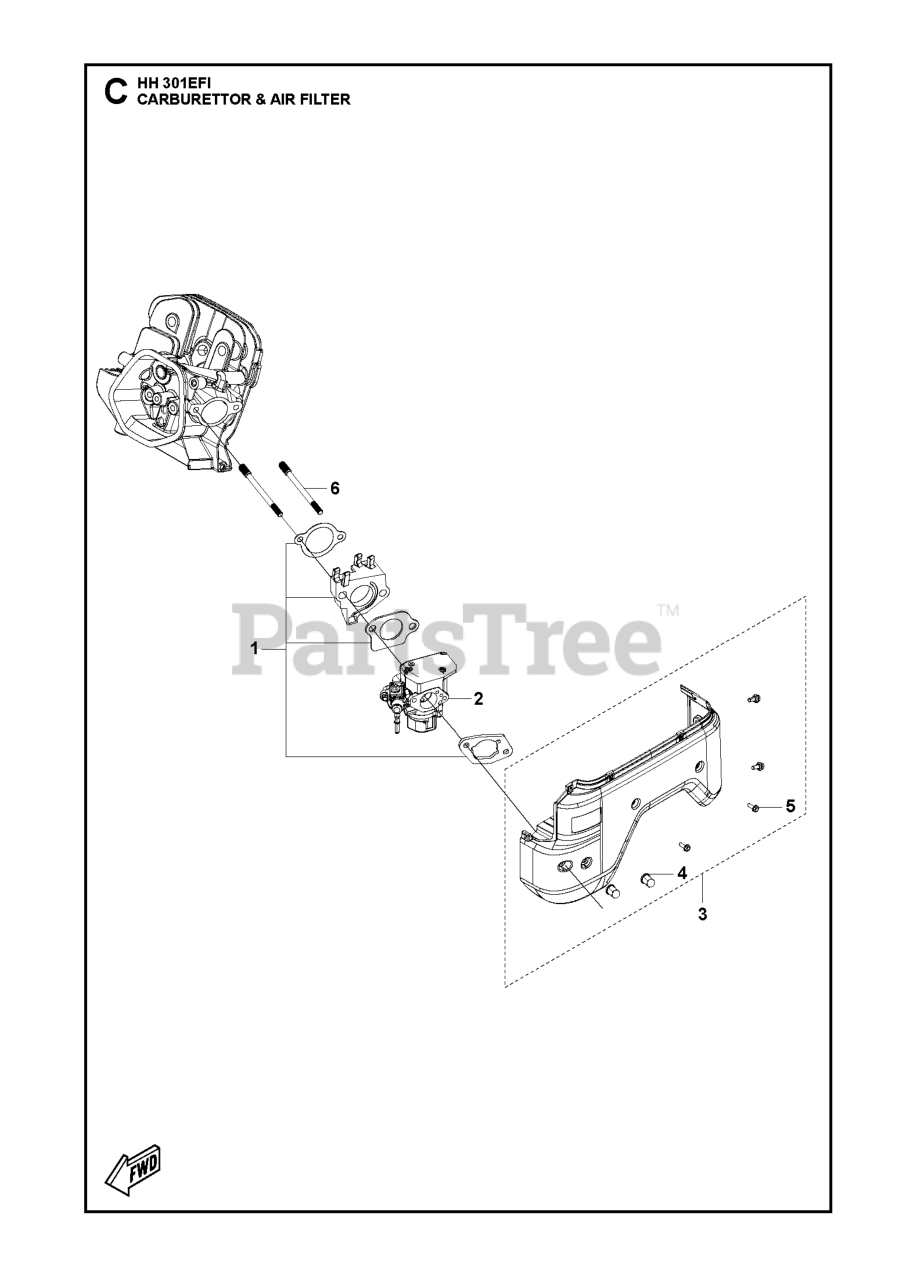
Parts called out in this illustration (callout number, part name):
1	GASKET KIT CARBURETTOR GASKET
2	ELECTRIC MODULE ECU
3	AIR FILTER ASSY
5	BOLT
